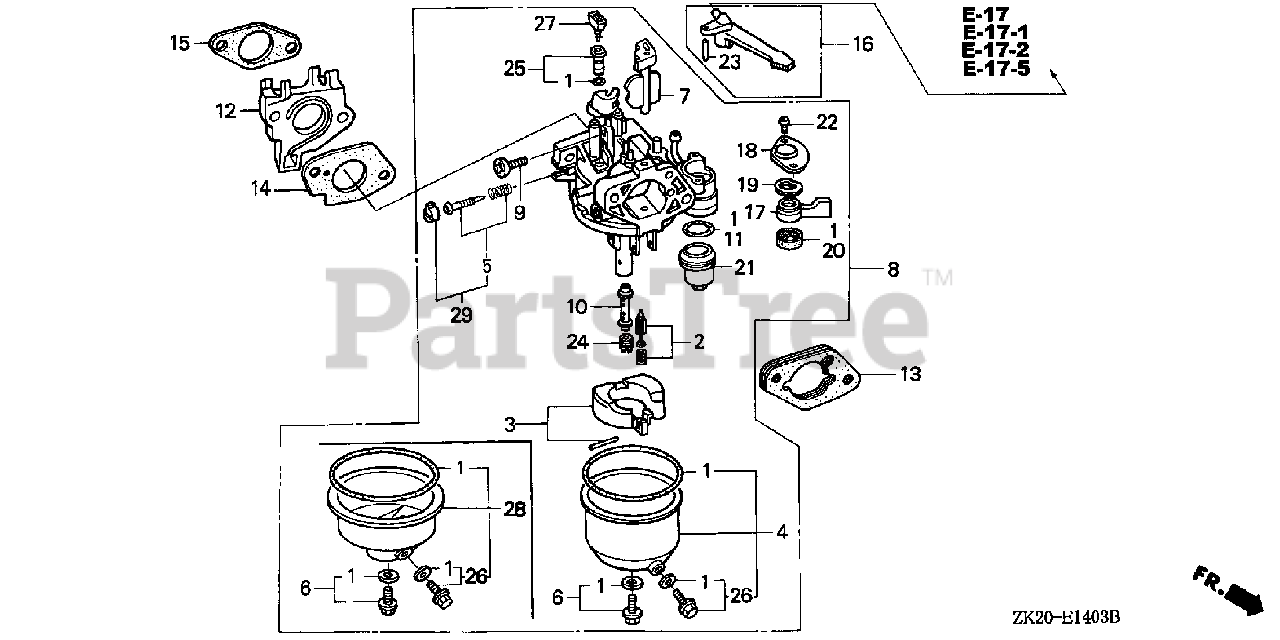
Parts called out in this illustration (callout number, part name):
1	GASKET SET
2	VALVE SET, FLOAT
3	FLOAT SET
6	SCREW SET B
7	CHOKE SET
8	CARBURETOR ASSY. (BE70B B)
9	SCREW, THROTTLE STOP
10	NOZZLE, MAIN
11	GASKET, FUEL STRAINER CUP
12	INSULATOR, CARBURETOR
13	SPACER, CARBURETOR
14	GASKET, CARBURETOR
15	GASKET, INSULATOR
16	LEVER, CHOKE (STD)
17	LEVER, VALVE
18	PLATE, LEVER SETTING
19	SPRING, VALVE LEVER
20	GASKET, VALVE
21	CUP, FUEL STRAINER
22	SCREW, PAN (3X6)
23	PIN, SPRING (2X12)
24	JET, MAIN (#82)
24	JET, MAIN (#85)
24	JET, MAIN (#88)
25	JET SET, PILOT (#40)
26	SCREW SET, DRAIN
27	COLLAR, SET
28	CHAMBER SET, FLOAT
29	SCREW SET
